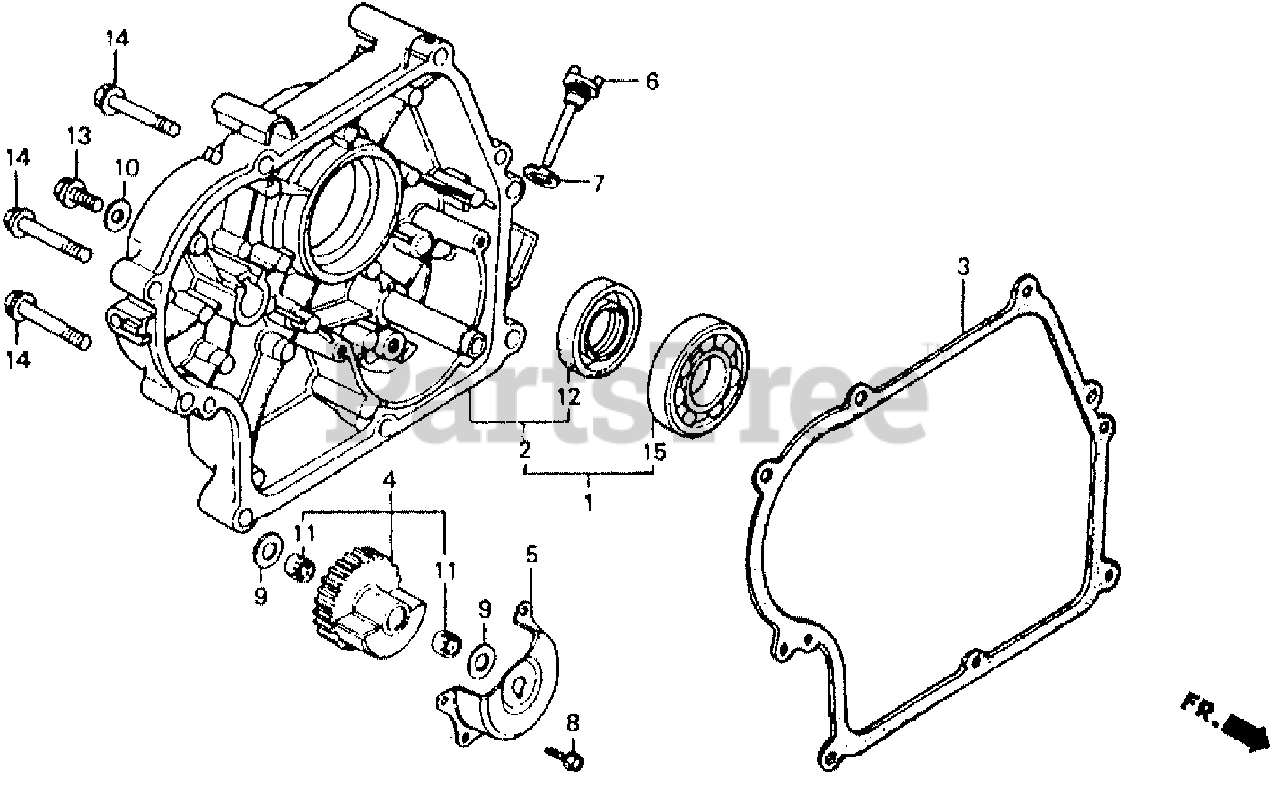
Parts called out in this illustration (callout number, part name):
1	COVER ASSY., CRANKCASE (V-TYPE)
2	COVER ASSY., CRANKCASE (V-TYPE)
3	GASKET, CASE COVER
4	WEIGHT, BALANCER
5	COVER, BALANCER
6	CAP, OIL FILLER
8	BOLT, FLANGE (6X12) (CT200)
8	BOLT, FLANGE (6X16)
9	WASHER, THRUST (15MM)
10	WASHER A (8MM)
11	BEARING, NEEDLE
12	OIL SEAL (30X46X8)
13	BOLT, FLANGE (8X12)
13	BOLT, FLANGE (8X14)
14	BOLT, FLANGE (8X45)
15	BEARING, RADIAL BALL (6206)
